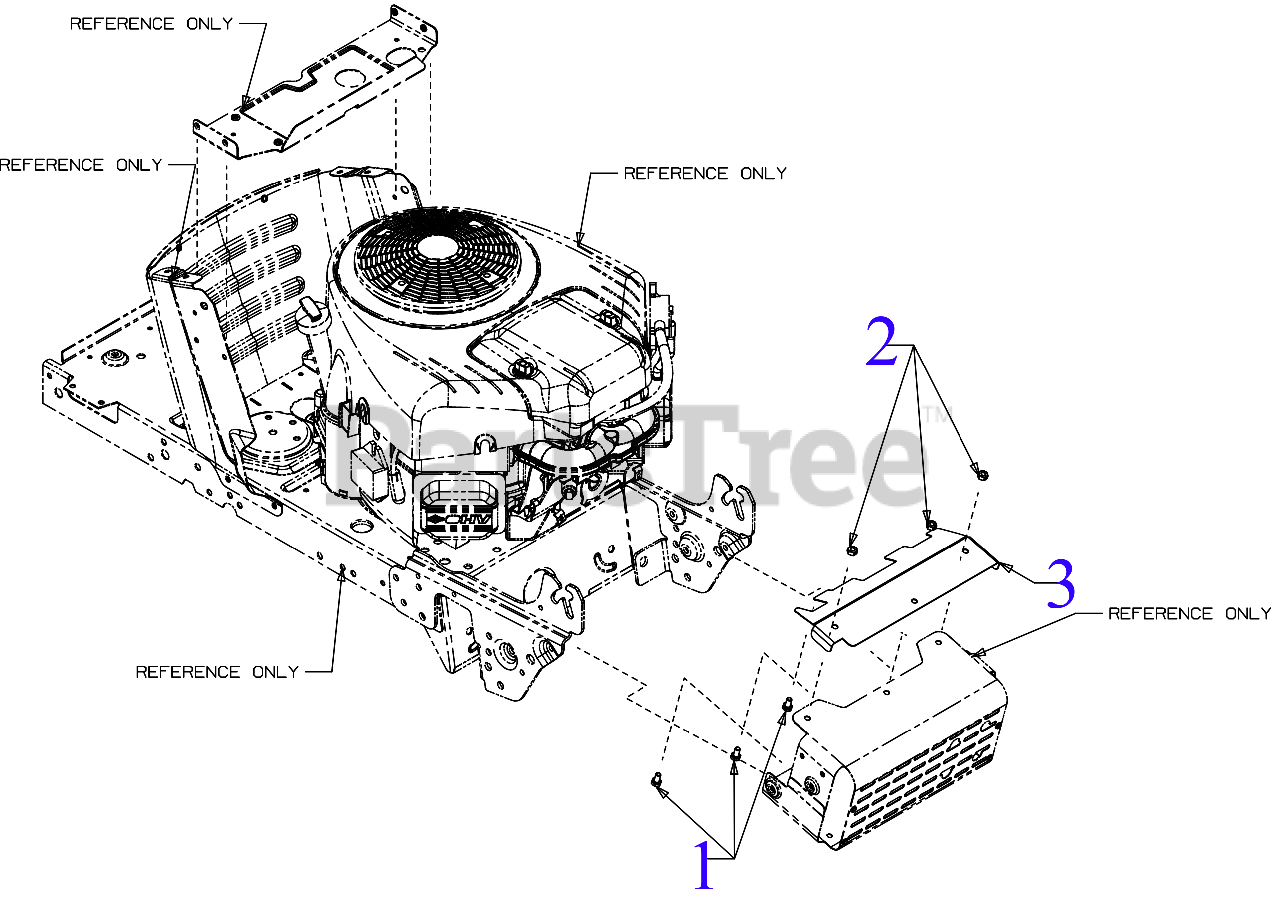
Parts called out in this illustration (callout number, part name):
1	SCREW 1/4-20X.5 GR5
2	HEX NUT
3	MUFFLER SHIELD EXTENSION
